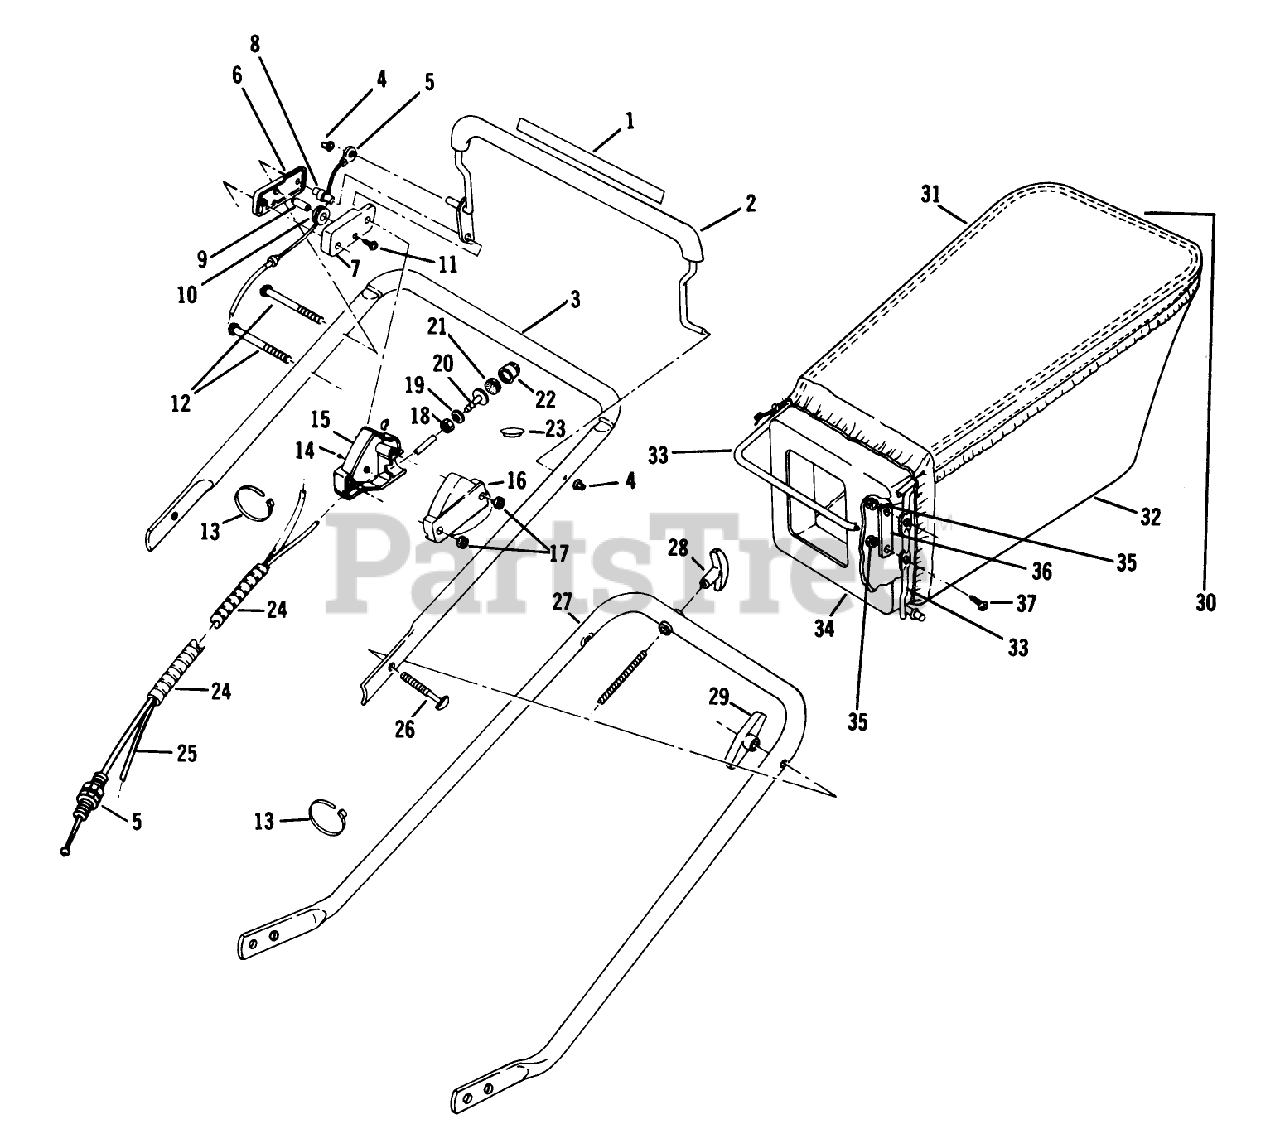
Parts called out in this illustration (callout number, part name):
5	CONTROL CABLE AY
8	COLUMN
9	PIN SKF
11	SCREW
14	SCREW LAWRENCE
17	NUT C/LOCK E
18	LOCKNUT S
21	FILTER S
25	PRIMER TUBING
26	BOLT QUALITY
28	HANDLE,STARTER
29	NUT-WING
31	HANGER BAG TROX
34	BAG ADAPTOR PL
35	LOCKNUT E
